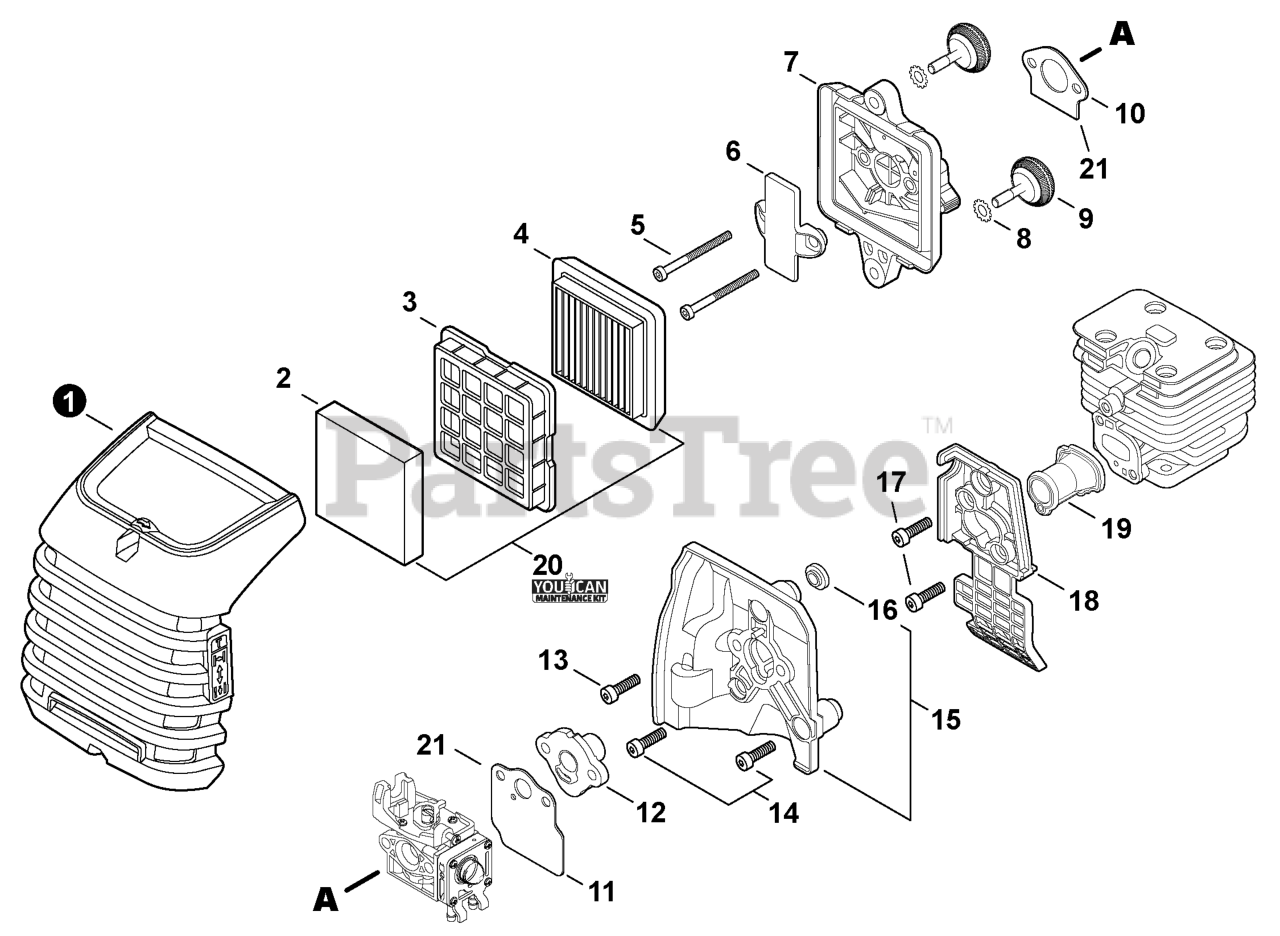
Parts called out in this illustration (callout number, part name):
1	COVER, AIR FILTER
2	PRE-FILTER, FOAM
3	RETAINER, PRE-FILTER
4	FILTER, AIR
5	BOLT, TORX 5x60
6	PLATE, PREVENT
7	CASE, AIR FILTER
8	WASHER, LOCK
9	THUMBSCREW
10	GASKET, INTAKE
11	HEAT SHIELD, INTAKE
12	BOOT, INSULATOR PLATE
13	BOLT, TORX 5x20
14	BOLT, TORX 5x16
15	PLATE, INSULATOR
16	COLLAR 5
17	SCREW 5x16
18	HOLDER, BELLOWS
19	BELLOWS, INTAKE
20	TUNE-UP KIT - YOUCANT
21	GASKET KIT: ENGINE, INTAKE, EXHAUST
